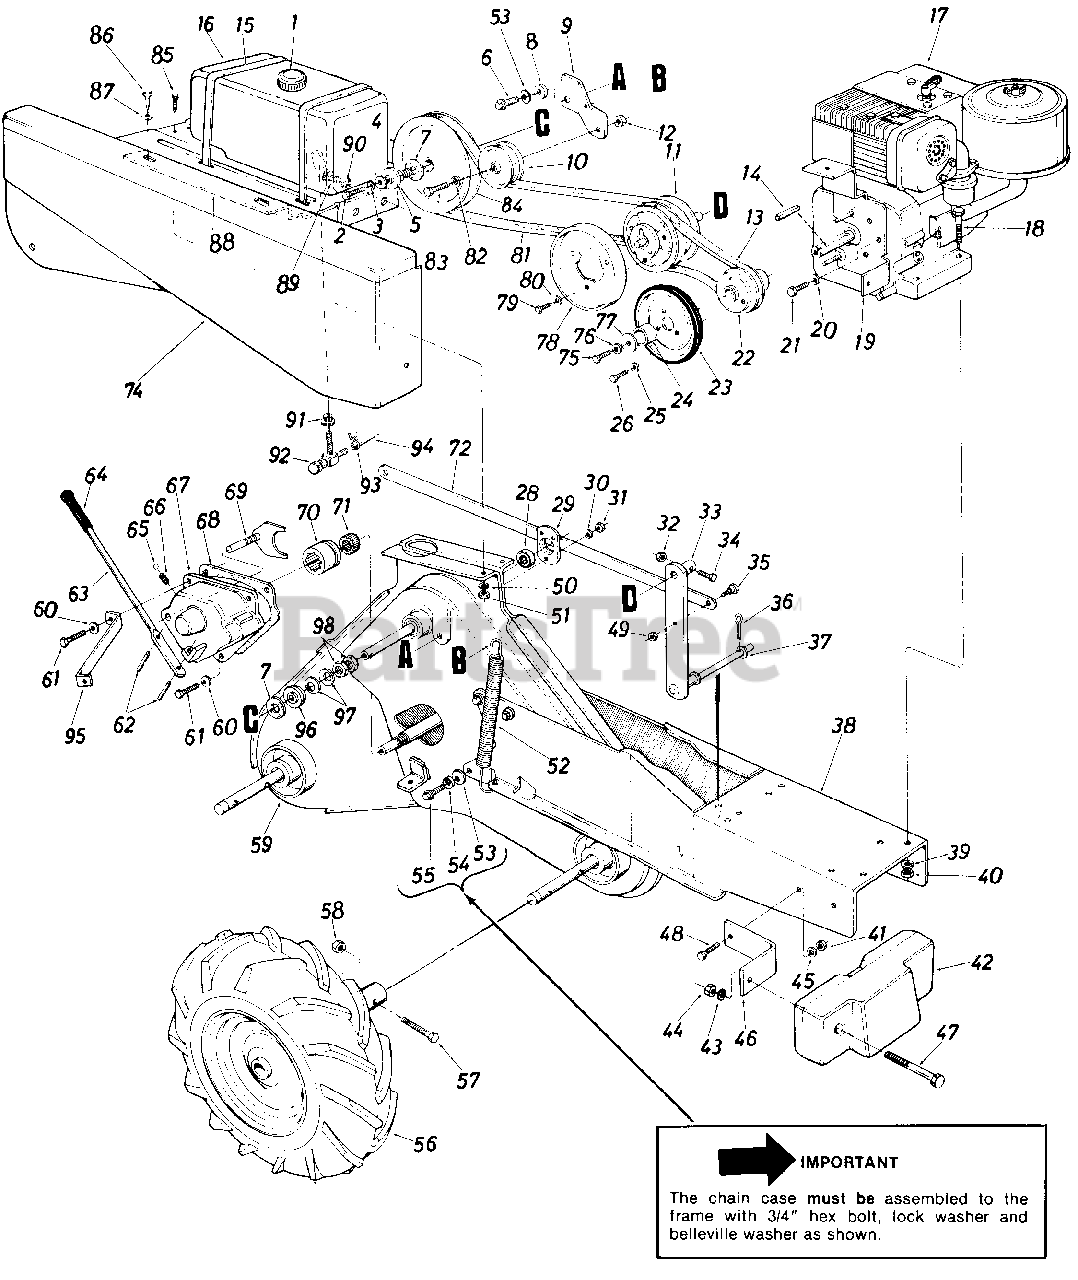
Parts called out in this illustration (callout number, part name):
1	Gas Cap
2	Hex L-Bolt 5/16-24 x 1.5" Lg.
3	L-Wash. 5/16" I.D.
4	Fl-Wash. 5/16" I.D. x 1.125" O.D.
5	Friction Disc Ass'y.
6	Hex Bolt 3/8-24 x 1.25" Lg.
7	Friction Pad
8	Shoulder Spacer
9	Idler Bracket
10	Fl-Idler 2.75" Dia.
11	Variable Speed Ass'y.
12	Hex Ins. L-Nut 3/8-16 Thd.
13	"V"-Belt 5/8" x 27.0" Lg.
14	Sq. Key 1/4" x 1.50" Lg.
15	Cable Tie
16	Gas Tank
17	Eng i ne
18	Hex Bolt 5/16-18 x 1.75" Lg.*
19	Belt Cover Support Ass'y.
20	Internal L-Wash. 1/2" I.D.
21	Hex Bolt 1/2-20 x .75" Lg.
22	Engine Pulley Ass'y.
23	Friction Wheel Ass'y.
24	Spacer
25	L-Wash. 5/16" I.D.
26	Hex Bolt 5/16-18 x .50" Lg.
28	Ball Bearing
29	Bearing Housing 1-3/8" O.D.
30	L-Wash. 1/4" I.D.
31	Hex Nut 1/4-28 Thd.
32	Hex Ins. L-Nut 1/4-20 Thd.
33	Variable Speed Brkt. Ass'y.
34	Hex Bolt 1/4-20 x 1.25" Lg.
35	Shld. Bolt 1/2" Dia. x .25" Lg.
36	Cotter Pin 118" Dia. x 1.0" Lg.*
37	Fl-Wash. .686" I.D. x 1.25" O.D.
38	Frame Ass'y.
39	L-Wash. 5/16" I.D.
40	Hex Nut 5/16-18 Thd.
41	Hex Cent. L-Nut 3/8-24 Thd.
42	Weight
43	Fl-Wash. .50" I.D. x 1.0" O.D.
44	Hex Nut 1/2-13 Thd.
45	L-Wash. 3/8" I.D.
46	Weight Mtg. Brkt.
47	Hex Bolt 1/2-13 x 4.50" Lg.
48	Hex Bolt 3/8-24 x 1.00" Lg.
49	Hex Ins. L-Nut 3/8-16 Thd.
50	L-Wash. 1/4n I.D.
51	Hex Cent. L-Nut 1/4-28 Thd.
52	Spring Idler Bracket
53	Belleville Wash. 3/8" I.D.
54	L-Wash. 3/8" I.D.*
55	Hex Self-Tap Scr. 3/8-16 x .75" Lg.
56	Wheel Ass'y. Comp.-R.H.
57	Hex Bolt 3/8-24 x 1.25" Lg.*
58	Hex Ins. L-Nut 3/8-24 Thd.
59	Chain Case Ass'y. Comp.
60	L-Wash. 5/16" I.D.*
61	Hex Tap Tite Scr. 5/16-18 x .75" Lg.
62	Headed Spiral Pin 3/16 x 13/16" Lg.
63	Engagement Lever
64	G ri p
65	Ball Detent.250" Dia.
66	Compression Spring
67	Shift Housing-R.H.
68	Gasket-Shift Housing
69	Shift Yoke Ass'y.-R.H.
70	Clutch Dog
71	Clutch Dog Driver
72	Control Brkt.
74	Shroud Belt Cover
75	Hex Bolt 7/16-20 x 1.00" Lg.
76	L-Wash. 7/16" I.D.
77	Fl-Wash. .44 I.D. x 1.38" O.D.
78	Friction Disc
79	Hex Bolt 1/4-28 x .50" Lg.
80	L-Wash. 1/4" I.D.*
81	"V"-Belt 5/8" x 51" Lg.
82	L-Wash. 3/8" I.D.*
83	Hex Bolt 3/8" x 1.50" Lg.*
84	Input Pulley-Chain Case
85	Hex Bolt 1/4-28 x .62" Lg.
86	Hex Wash. Hd. Self-Tap Scr.
87	Fl-Wash. 1/4" I.D.
88	Tank Mounting Brkt.
89	Hex Bolt 5/16-18 x .75" Lg.*
90	L-Wash. 5/16" I.D.*
91	Bushing-Gas Line
92	Shut-Off Valve
93	Clamp Gas Line
94	Gas Line 14-1/2" Lg.
95	Brace
96	Floating Disc
97	Spring Bell-Wash.
98	Hex Jam Nut 1.0-14
